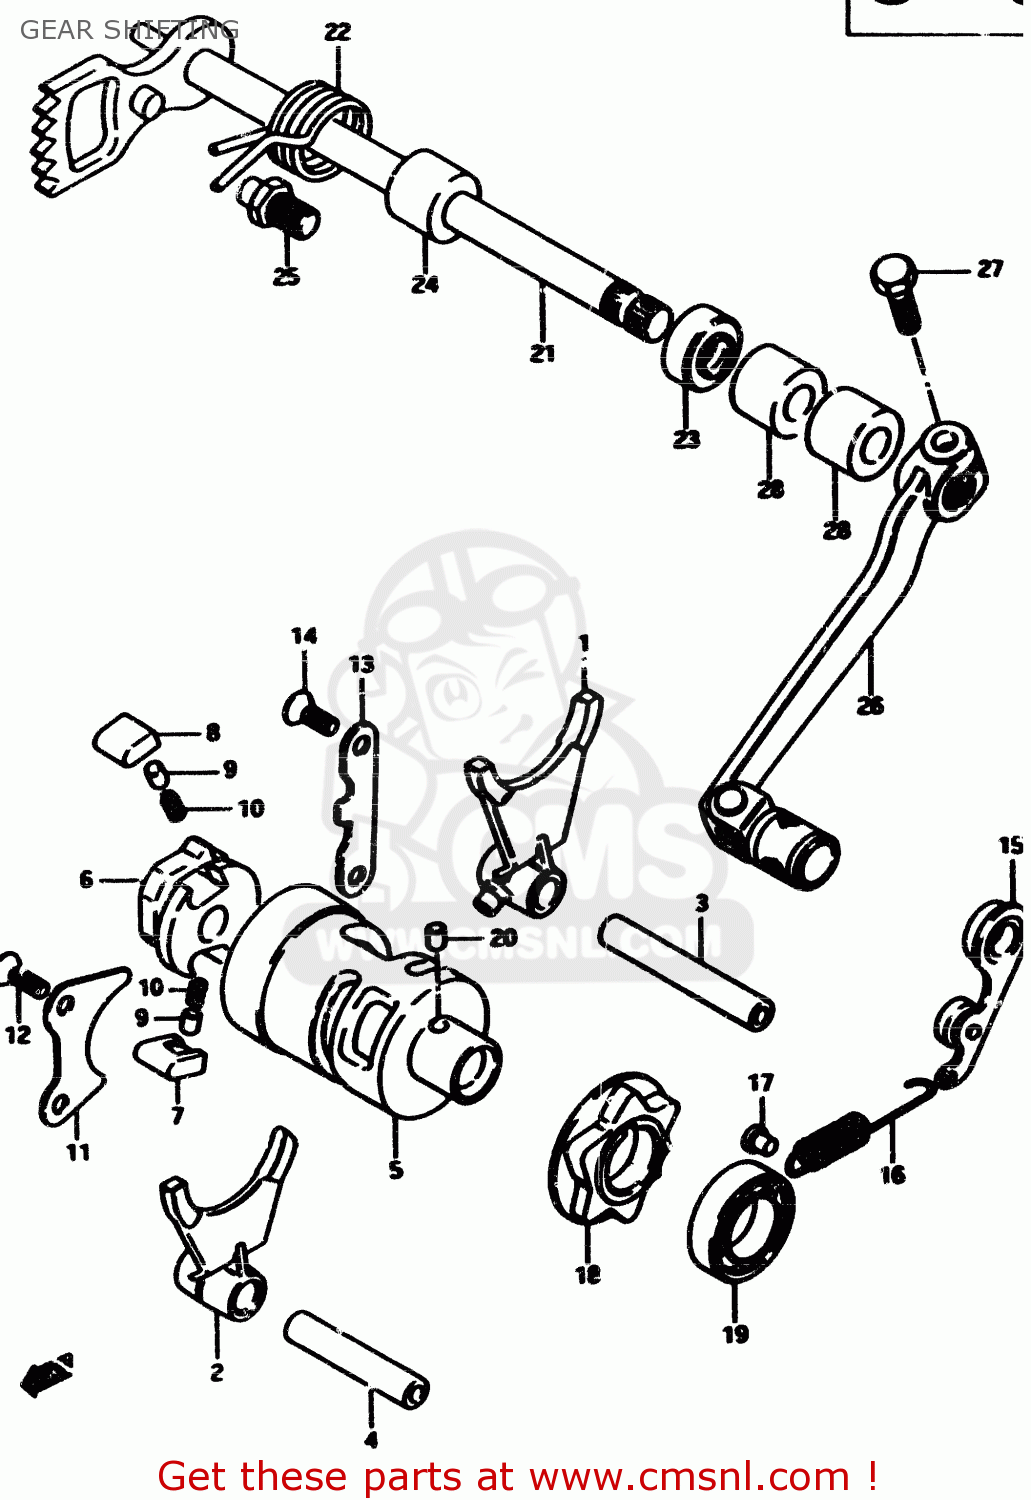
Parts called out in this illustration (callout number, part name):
1	FORK,GEAR SHIFT NO.1
2	FORK,GEAR SHIFT NO.2
3	SHAFT,GEAR SHIFT FORK NO.2
4	SHAFT,GEAR SHIFT FORK
5	CAM,GEAR SHIFT
6	GEAR,GEARSHIFT CAM DRIVE
7	PAWL,GEAR SHIFT NO.1
8	PAWL,GEAR SHIFT NO.2
9	PIN(5X8)
10	SPRING
11	LIFTER,GEAR SHIFT PAWL
12	SCREW
13	STOPPER,GEAR SHIFT POLE
14	SCREW
15	STOPPER,GEAR SHIFTING
16	SPRING
17	RIVET
18	PLATE,GEAR SHIFT CAM STOPPER
19	BEARING
20	PIN
21	SHAFT,GEAR SHIFT
22	SPRING
23	OIL SEAL
24	SPACER(12X20X15.3)
25	STOPPER,GEAR SHIFT CAM
26	LEVER ASSEMBLY,GEAR SHIFTING
27	BOLT
28	SPACER(12X20X15.3)
